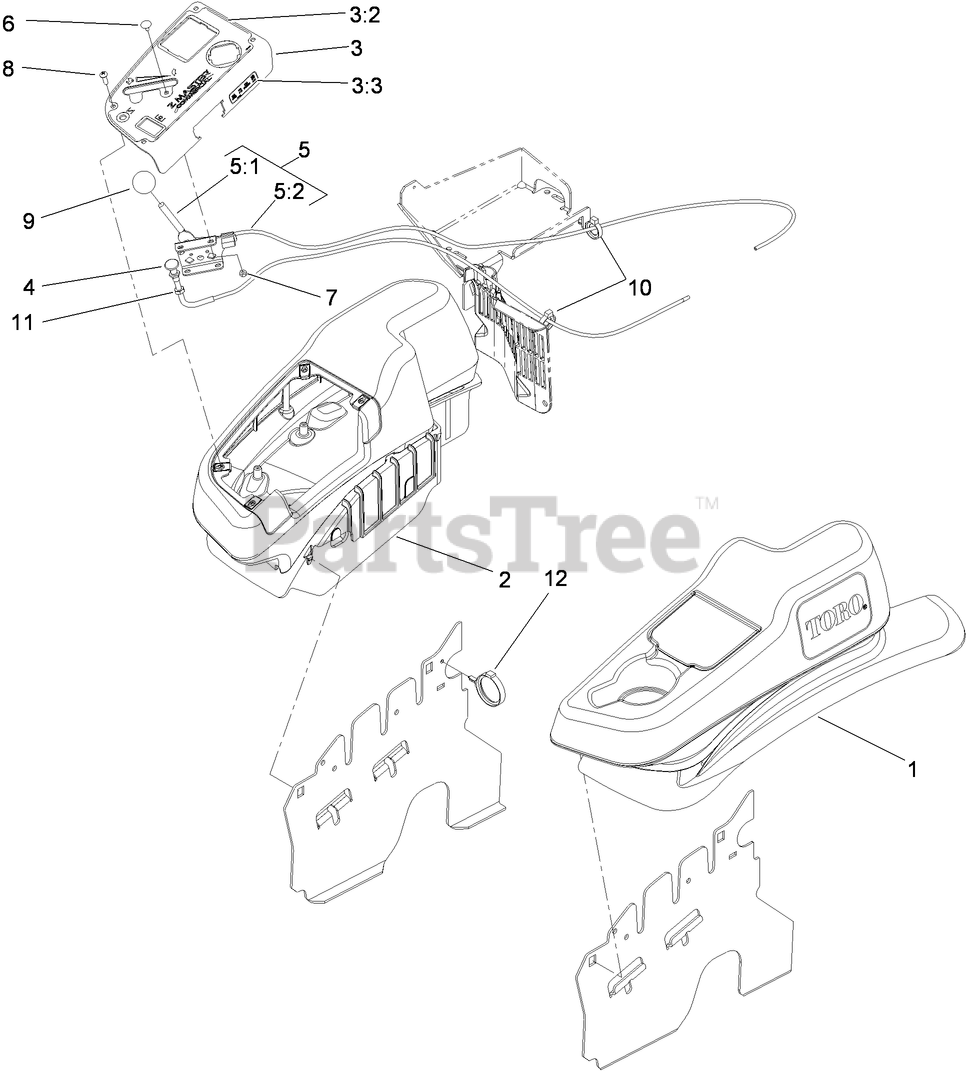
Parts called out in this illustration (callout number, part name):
1	LH NARROW FENDER/CONSOLE ASM
2	RH NARROW FENDER/CONSOLE ASM
3	CONTROL PANEL ASM
3:2	DECAL-PANEL, CONTROL
3:3	DECAL-FUSES
4	CHOKE CONTROL ASM
5	THROTTLE CONTROL ASM
5:1	LEVER-THROTTLE
5:2	CABLE-THROTTLE
6	BOLT-CARR
7	NUT-LOCK, NI
8	SCREW-HWH
9	KNOB-BALL
10	CLAMP-HOSE
11	NUT-HJ
12	CLAMP-HARNESS
